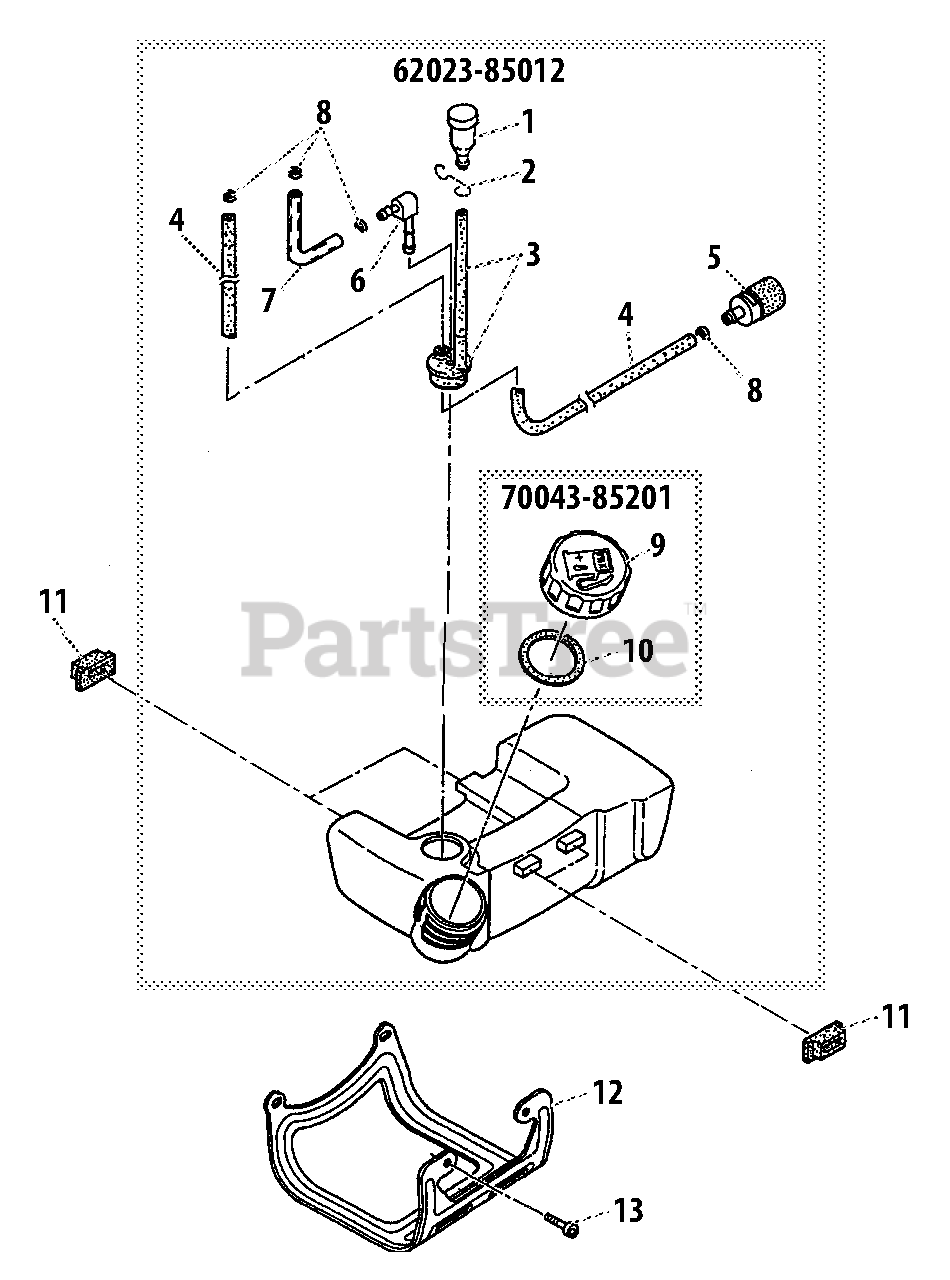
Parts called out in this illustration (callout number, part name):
1	VENT, FUEL TANK
2	HOLDER, VENT
3	VENT PIPE ASSY
4	PIPE - FUEL
5	FILTER, FUEL
6	CONNECTOR, PIPE
7	PIPE - RETURN
8	RING, RETAINING - 6
9	CAP, FUEL
10	GASKET, CAP
11	CUSHION, TANK
12	GUARD, FUEL TANK
13	SCREW - 5X12
62023-85012	FUEL TANK ASSY
70043-85201	CAP ASSY
